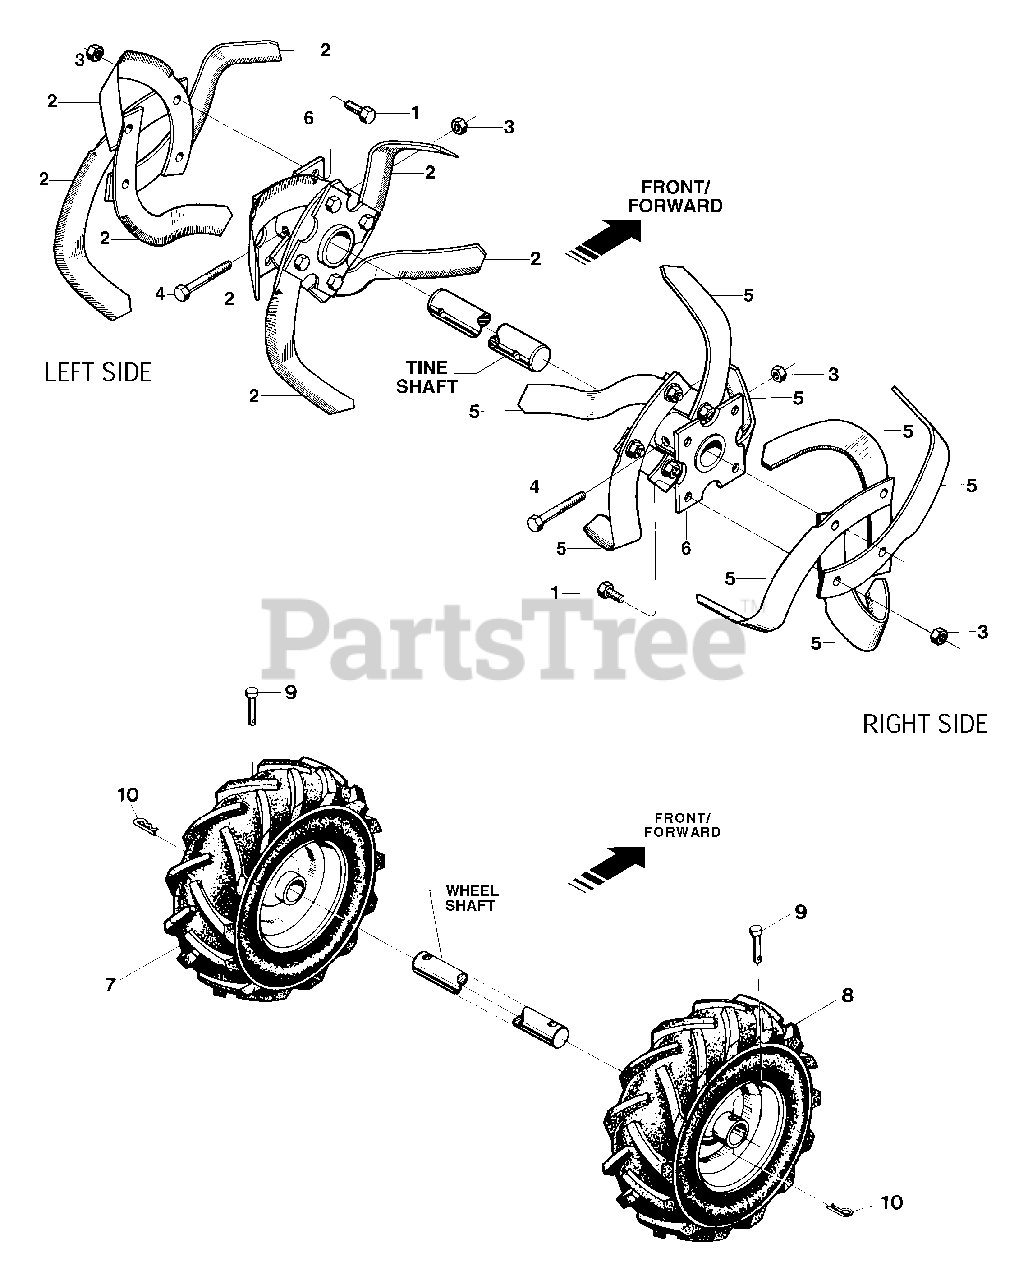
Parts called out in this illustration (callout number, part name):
1	Hex Screw, 3/8-16 x 1, Grade 5, Tine Mounting
2	Bolo Tine- Single, Right Hand tine - used on left side of tiller.
3	Hex Locknut, 3/8-16
4	Hex Screw, 3/8-16 x 1-3/4 (tine holder to tiller shaft)
5	Bolo Tine-Single, Left Hand tine - used on right side of tiller.
6	Tine Holder-for bolo tines, left and right sides
7	Wheel & Tire Assy-Left Side
8	Wheel & Tire Assy-Right Side
9	Clevis Pin-.312" x 1-3/4"
10	Hair Pin Cotter
